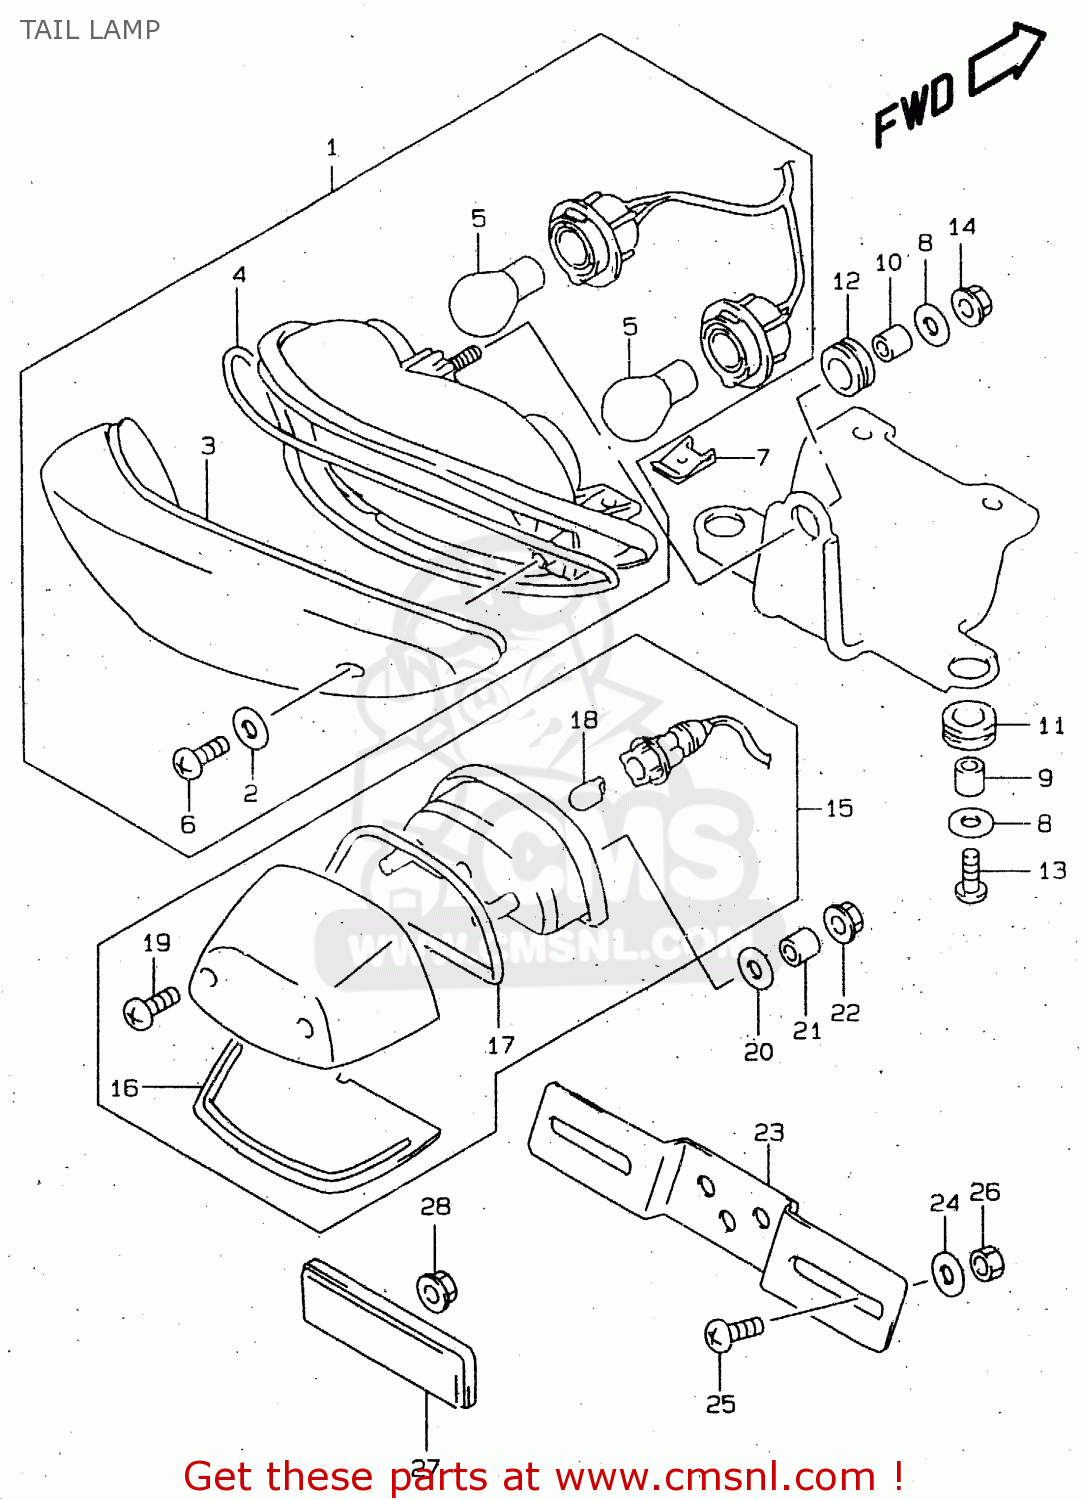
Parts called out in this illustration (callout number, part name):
1	LAMP ASSY,RR COMBINATION
2	GASKET (NAS)
3	LENS
4	GASKET (NAS)
5	BULB(12V21/5W)
6	SCREW
7	NUT
8	WASHER(6.5X20X1.6)
9	SPACER(6.5X10X9)
10	SPACER(6.5X10X12)
11	CUSHION
12	CUSHION
13	SCREW
14	NUT
15	LAMP ASSY,LICENSE
16	LENS
17	GASKET (NAS)
18	BULB(12V5W)
19	SCREW
20	WASHER(6.5X20X1.6)
21	SPACER(5.5X9.5X11.5)
22	NUT
23	BRACKET,LICENSE PLATE
24	WASHER(6.5X20X1.6)
25	SCREW
26	NUT
27	REFLECTOR ASSEMBLY,REAR
28	NUT
